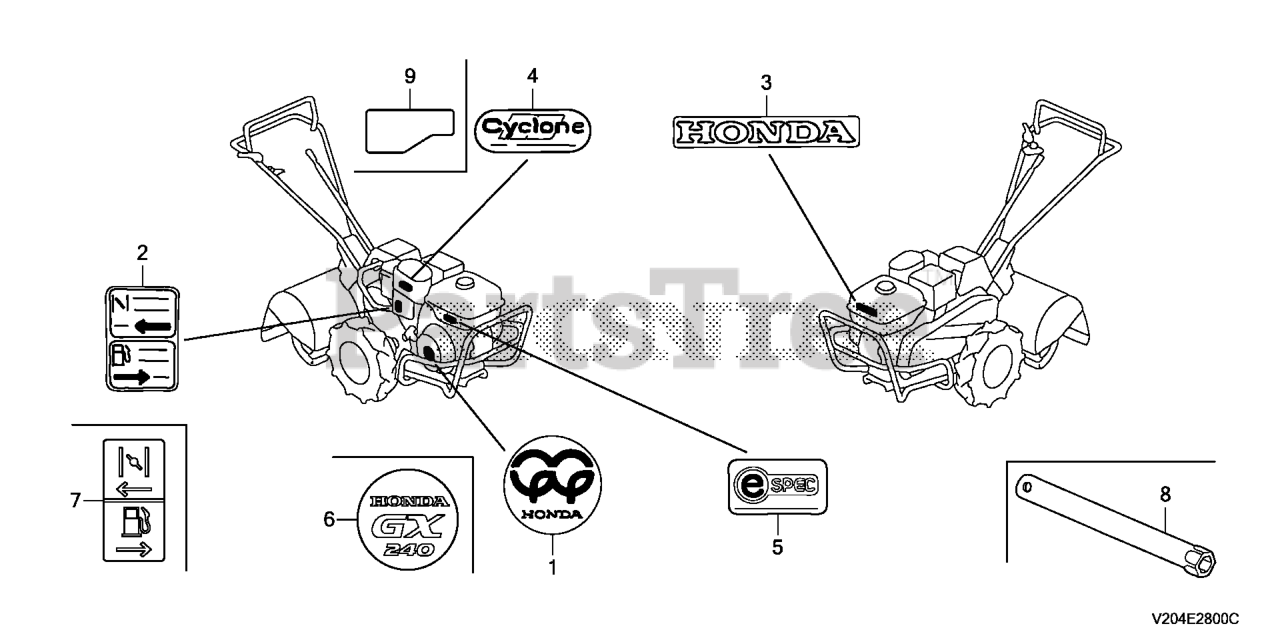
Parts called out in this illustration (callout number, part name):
1	PLATE, EMBLEM
2	MARK, CHOKE
3	MARK, HONDA EMBLEM (12 (HONDA)
4	MARK, AIR CLEANER SALES POINT
